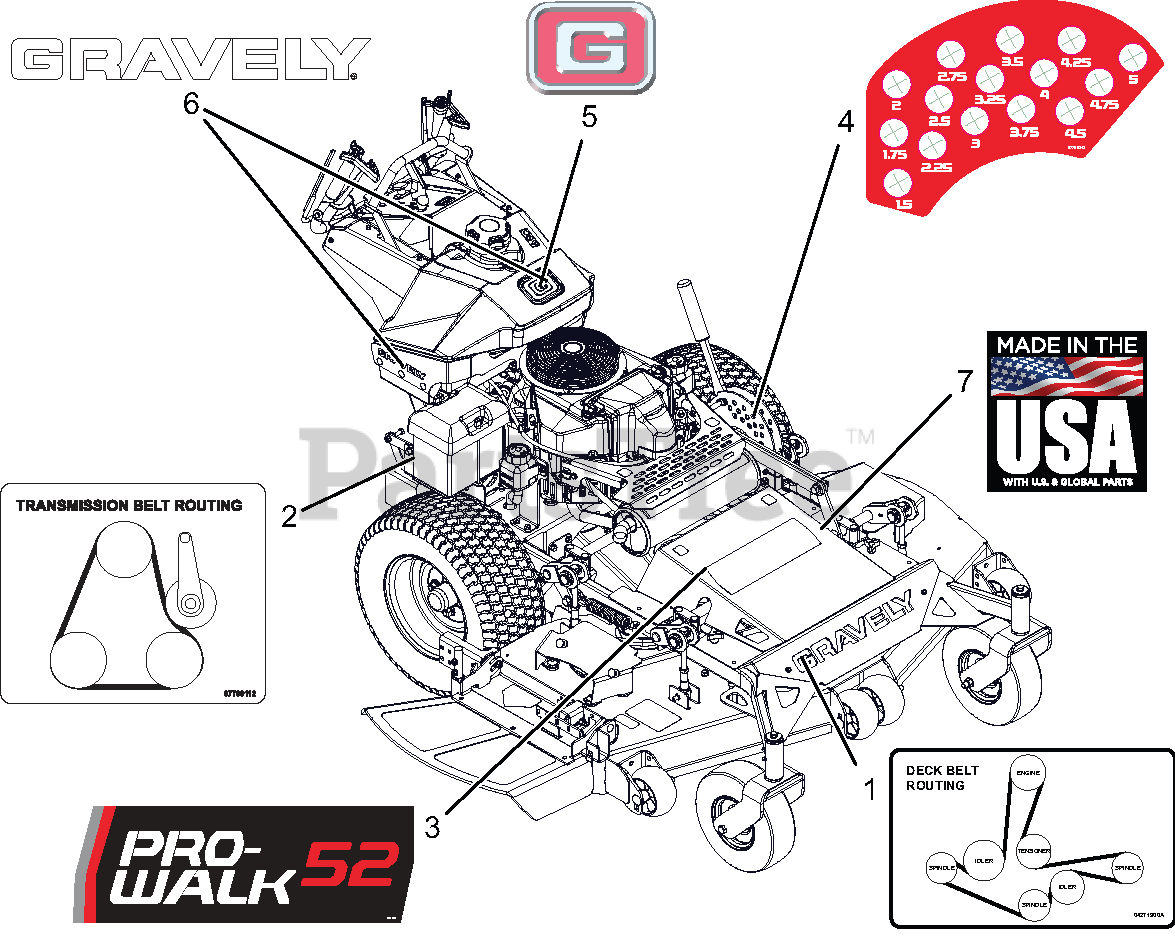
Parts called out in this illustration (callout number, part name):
1	DECAL, BELT ROUTING
2	DECAL, HYDRO BELT 36 PROSTANCE
3	DECAL, PRO WALK 52"
4	DECAL, HOC
5	DECAL, GRAVELY BRAND
6	DECAL, 6.5" GRAVELY LOGO
7	DECAL, MADE IN USA
